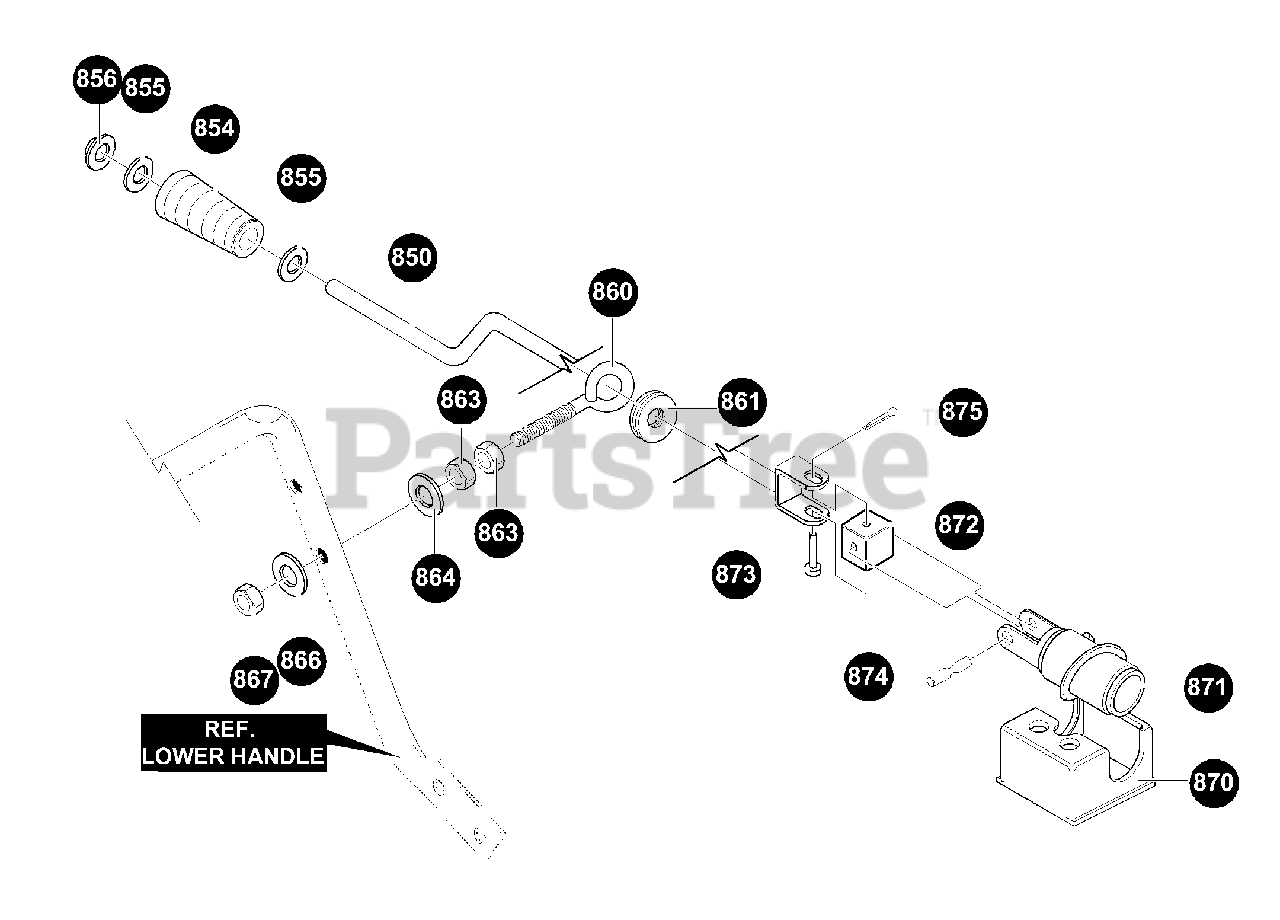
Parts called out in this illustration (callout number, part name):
850	CRANK ASSY W/YOKE
854	KNOB, SLEEVE
855	FLATWASHER .406X.81X.065
856	NUT, PUSH ON 3/8"
860	EYE BOLT, 3/8-16X6.00
861	GROMMET, EYE BOLT
863	NUT, 3/8-16 HEXJAM
864	FLATWASHER .406X.81X.065
866	FLATWASHER, .406X.81X.065
867	NUT, 3/8-16 REGHEX
870	BRACKET, WORM MOUNTING
871	WORM GEAR CHUTE ROTATE
872	BLOCK, UNIV. PIVOT
873	PIN, CLEVIS
874	PIN, UNIV. JOINT
875	COTTER PIN .06X.50
